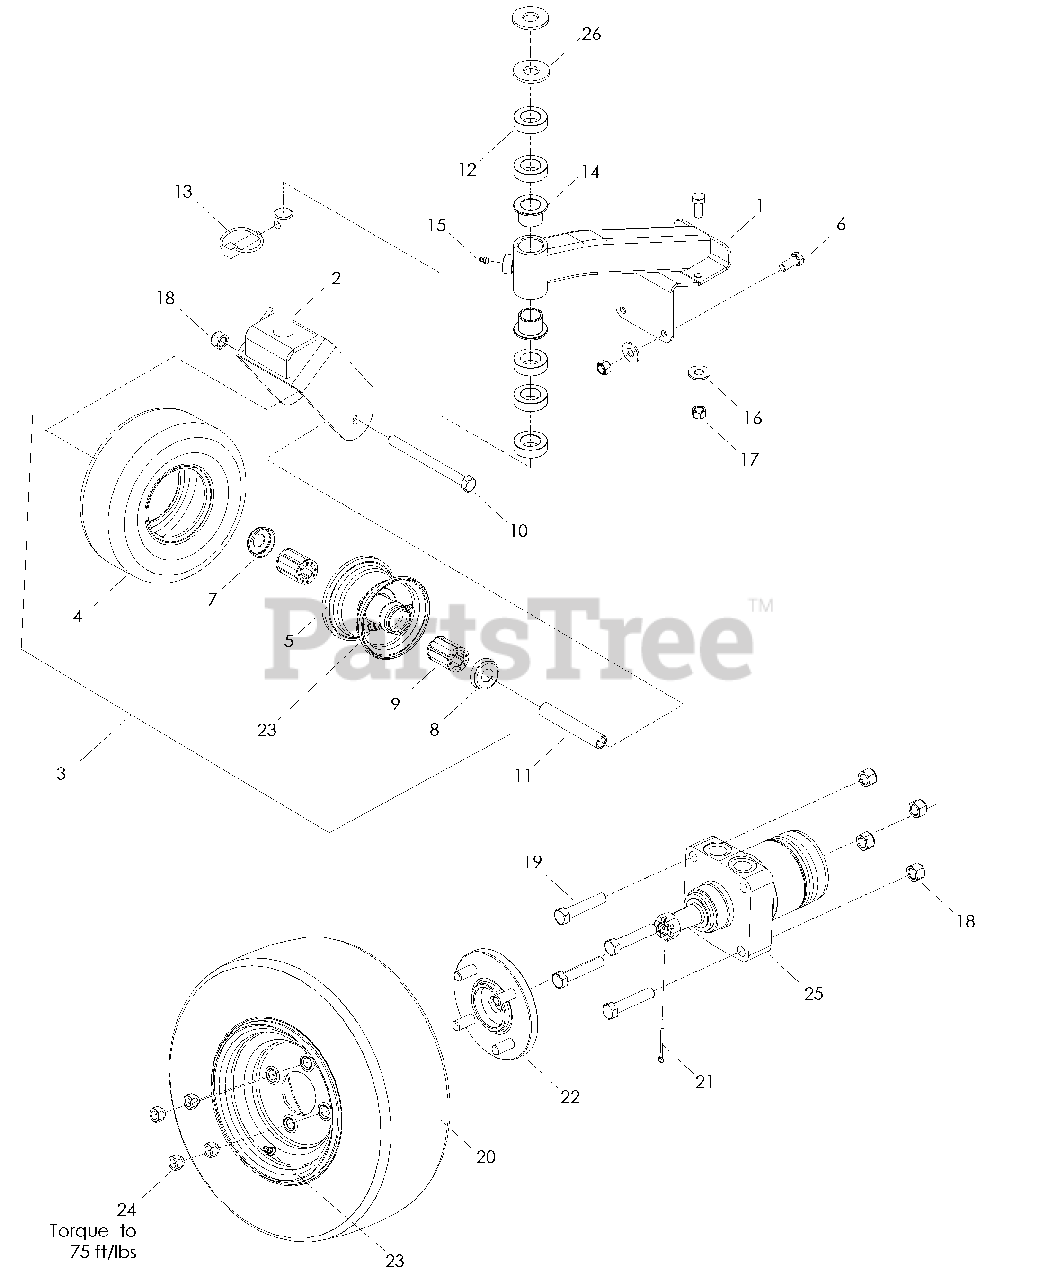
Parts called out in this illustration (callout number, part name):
1	CASTER ARM
2	CASTER FORK
3	WHEEL ASSEMBLY, CASTER
4	TIRE, CASTER
6	HCS 3/8-16 x 7/8
7	ENDCAP
8	NOTCHED ENDCAP
9	ROLLER BEARING
10	HCS 1/2-13 x 5 1/2
11	SPACER, CASTER
12	SPACER, HEIGHT
13	LYNCH PIN 7/16
15	ZERK
16	WASHER 3/8 FLAT
17	NUT 3/8-16 HEX NYLOC
18	NUT 1/2 HEX NYLOC
19	HCS 1/2-13 x 2 1/2
20	WHEEL ASSM, REAR 36
21	PIN 1/8 x 1 1/2 COTTER
22	HUB, WHEEL
24	NUT, LUG 1/2
26	SPACER, HT ADJ 1/4
